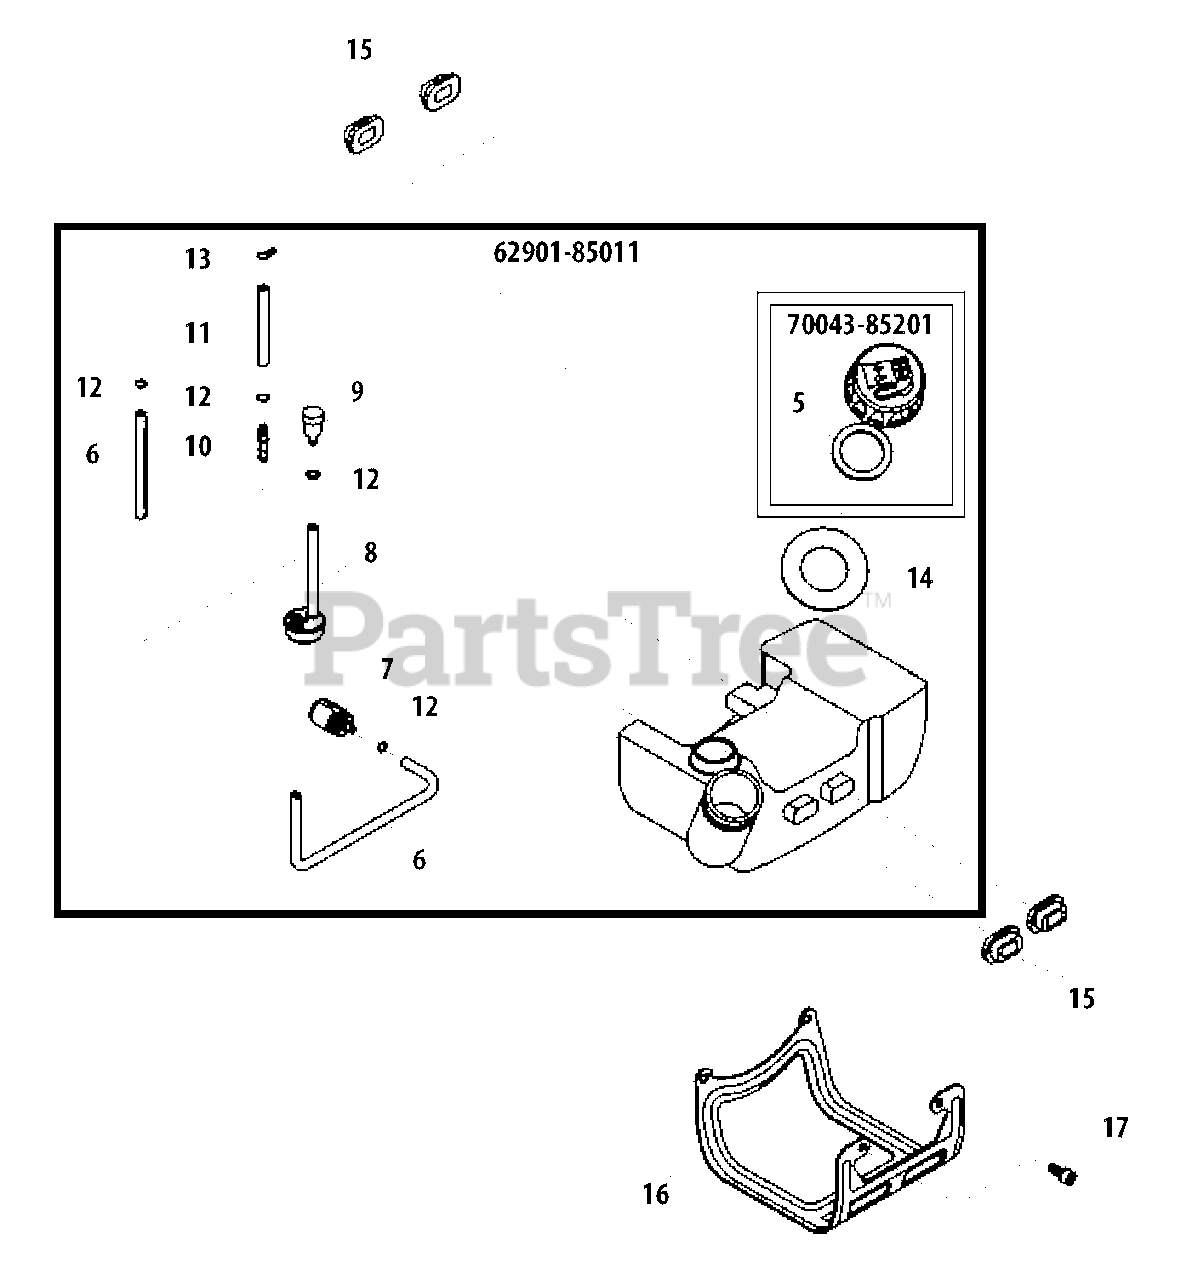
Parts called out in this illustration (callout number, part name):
5	GASKET, CAP
6	PIPE - FUEL
7	FILTER, FUEL
8	GROMMET
9	ELEMENT, BREATHER
10	CONNECTOR, PIPE
11	PIPE - RETURN
12	RING, RETAINING - 6
13	CLIP - SPRING
14	PLATE, CAUTION
15	CUSHION, FUEL TANK
16	GUARD, FUEL TANK
17	SCREW - 5X8
62901-85011	FUEL TANK ASSY
70043-85201	CAP ASSY
